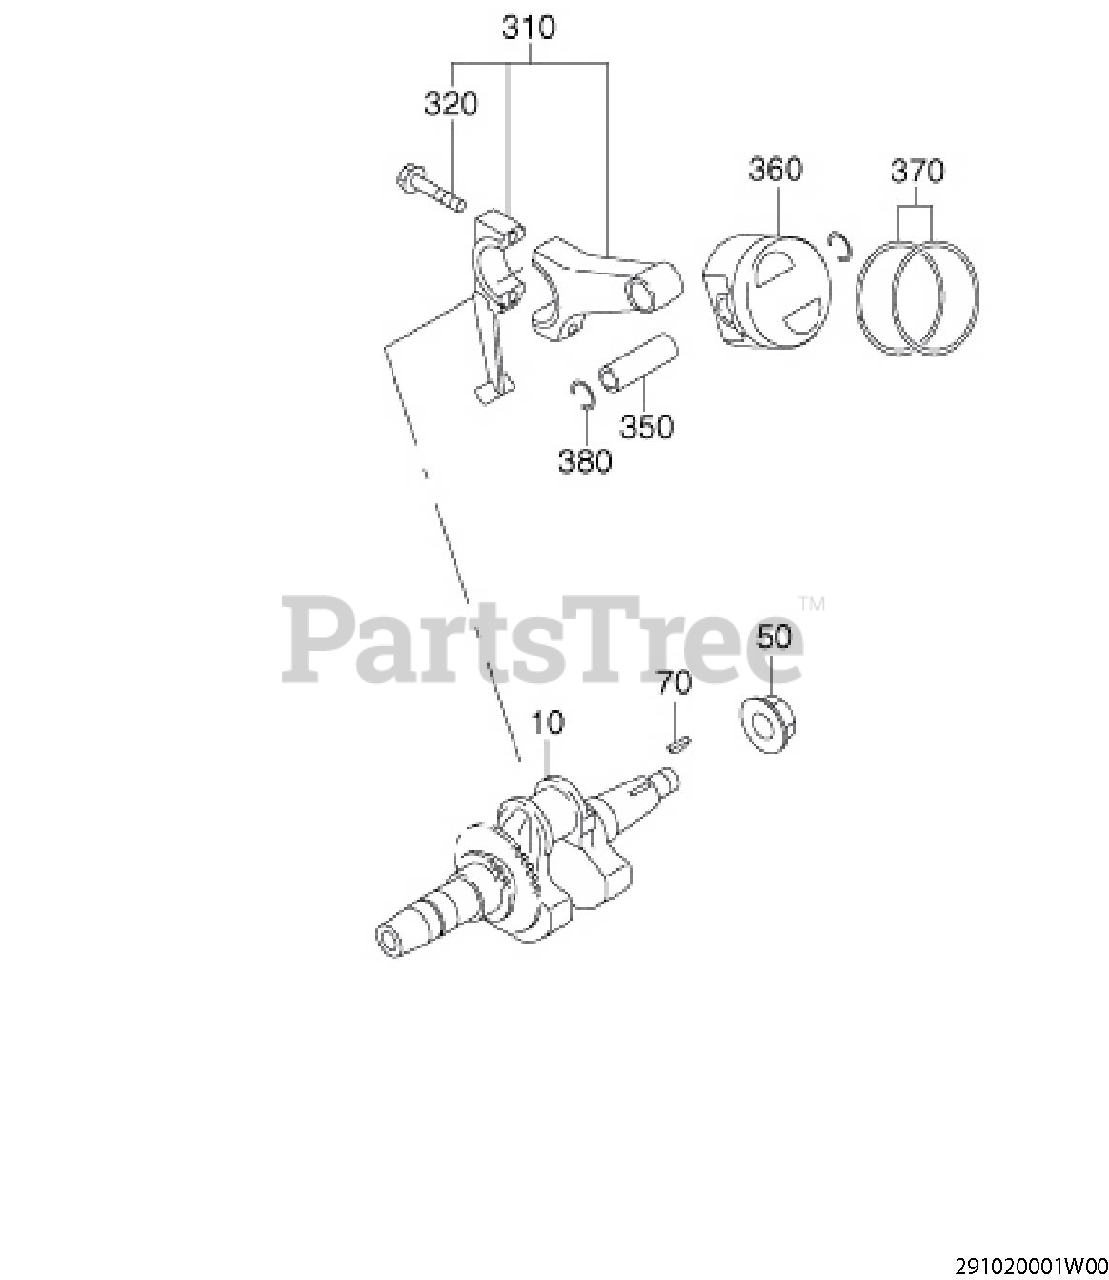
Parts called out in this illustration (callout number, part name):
10	CRANK SHAFT CP
50	FLANGE NUT
70	WOODRUFF KEY
310	CONNECTING ROD AY
320	CONNECTING ROD BOLT
350	PISTON PIN
360	PISTON
370	PISTON RING SET
380	CLIP
